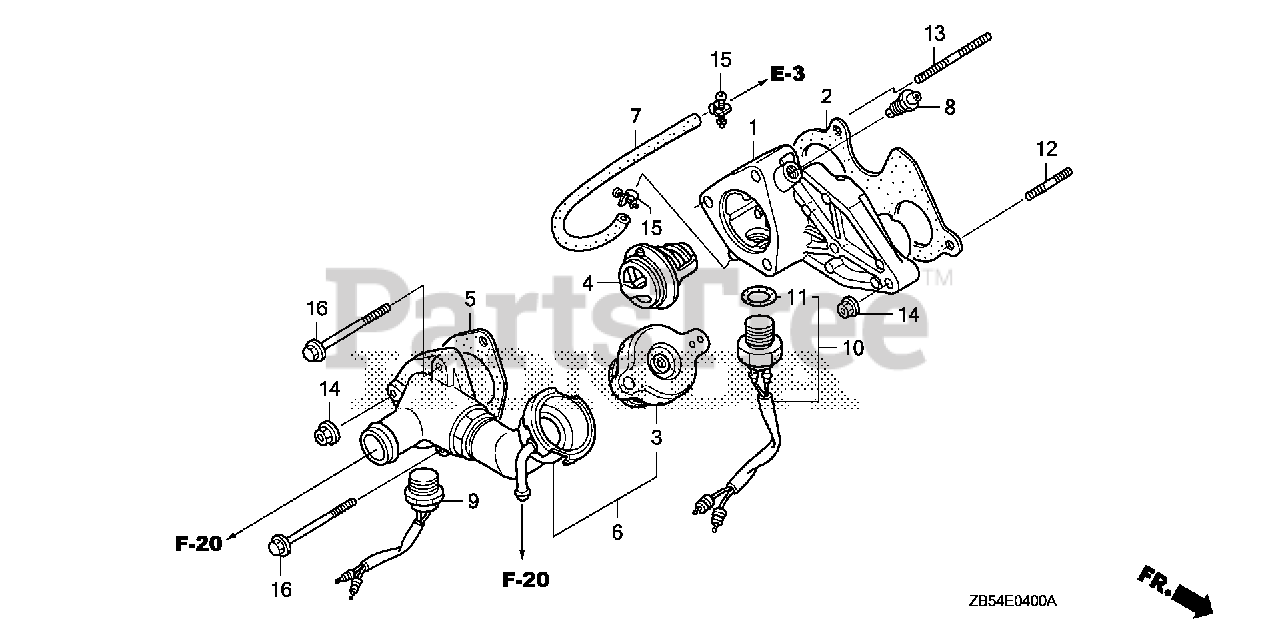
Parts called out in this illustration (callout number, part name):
1	CASE, THERMOSTAT
2	GASKET, GOVERNOR CASE
3	CAP, RADIATOR FILLER
4	THERMOSTAT ASSY.
5	GASKET, THERMOSTAT COVER
6	COVER, THERMOSTAT
7	HOSE, WATER BYPASS
8	BOLT, BREATHING WATER
9	SWITCH, ENGINE THERMOSTAT (NIPPON THERMOSTAT)
10	SWITCH, THERMOSTAT SOLENOID
11	O-RING (15.5X1.4)
12	BOLT, STUD (6X25)
13	BOLT, STUD (6X60)
14	NUT, FLANGE (6MM)
15	CLIP, TUBE (D12.5)
16	BOLT, FLANGE (6X65)
